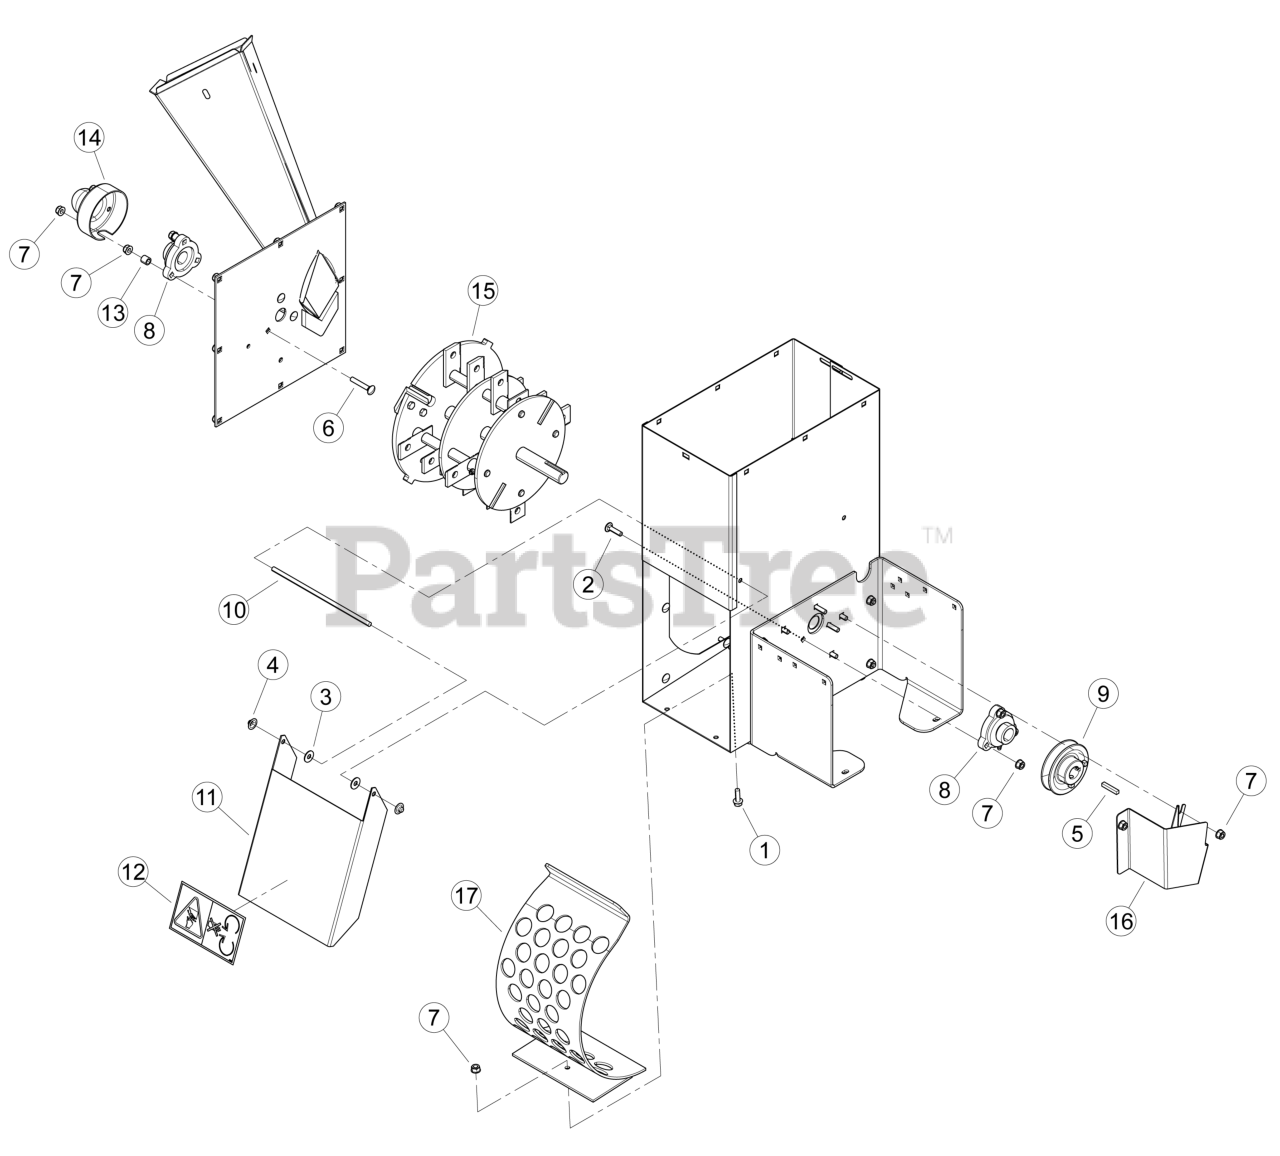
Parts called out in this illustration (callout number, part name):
1	BOLT, 5/16 × 1 FLANGE NC
2	BOLT, 5/16 × 1-1/4 GR5 CRG
3	WASHER, 5/16" ID 7/8" OD NYLON FLAT
4	PUSHNUT, 5/16" ZP
5	KEY, 1/4 SQ × 1-1/2 LG PLAIN
6	BOLT, 5/16 × 2" GR5 CRG NC ZP
7	NUT, 5/16-18 NYLOCK FLANGE
8	BEARING, 1" FLUSH MOUNT CAST W/ COLLAR
9	PULLEY, CAST 4" OD 1" BORE B GRV
10	SHAFT, DOOR PIVOT
11	DOOR, DISCHARGE 8 HP W/ DECAL
12	DECAL, BLADE DANGER ISO
13	SPACER, .54 OD × .50" LG
14	CAP, ROTOR SHAFT END CAP RENTAL
15	ASSEMBLY, WIDE ROTOR W/ RECT KNIVES
16	SHIELD, LOWER
17	WELDMENT, WIDE COARSE TAPERED
